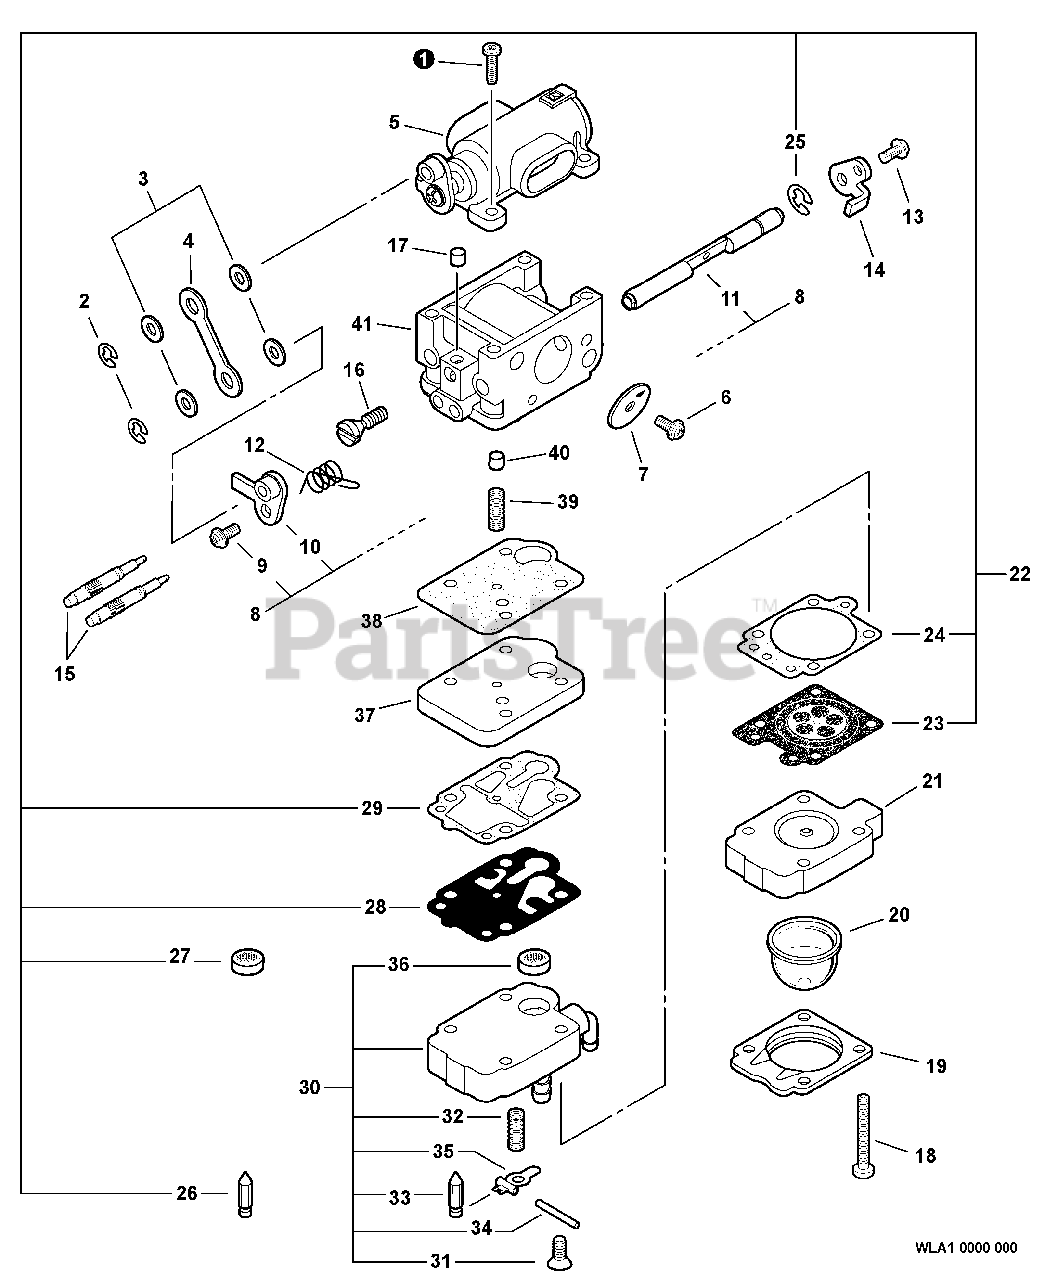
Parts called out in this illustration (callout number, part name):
2	RING, RETAINING
5	AIR VALVE ASSY
7	VALVE, THROTTLE
8	THROTTLE SHAFT ASSY
10	LINK, THROTTLE
11	SHAFT, THROTTLE
14	LEVER, CHOKE
15	NEEDLE - MIXTURE
16	SCREW, IDLE ADJUST
18	SCREW, IDLE ADJUST
19	RETAINER, PURGE BULB
20	BULB, PURGE
21	PURGE BASE ASSY
22	REPAIR KIT
23	DIAPHRAGM, METERING
24	GASKET, METERING
25	RING, RETAINING
26	VALVE, INLET NEEDLE
27	STRAINER
28	DIAPHRAGM, PUMP
29	GASKET, PUMP
30	PURGE BASE ASSY
31	SCREW, METERING LEVER PIN
32	SPRING, METERING LEVER
33	VALVE, INLET NEEDLE
34	PIN, METERING LEVER
35	LEVER, METERING
36	STRAINER
37	PLATE, PASSAGE
38	GASKET, PASSAGE
40	PISTON ASSY
41	BODY, CARBURETOR
